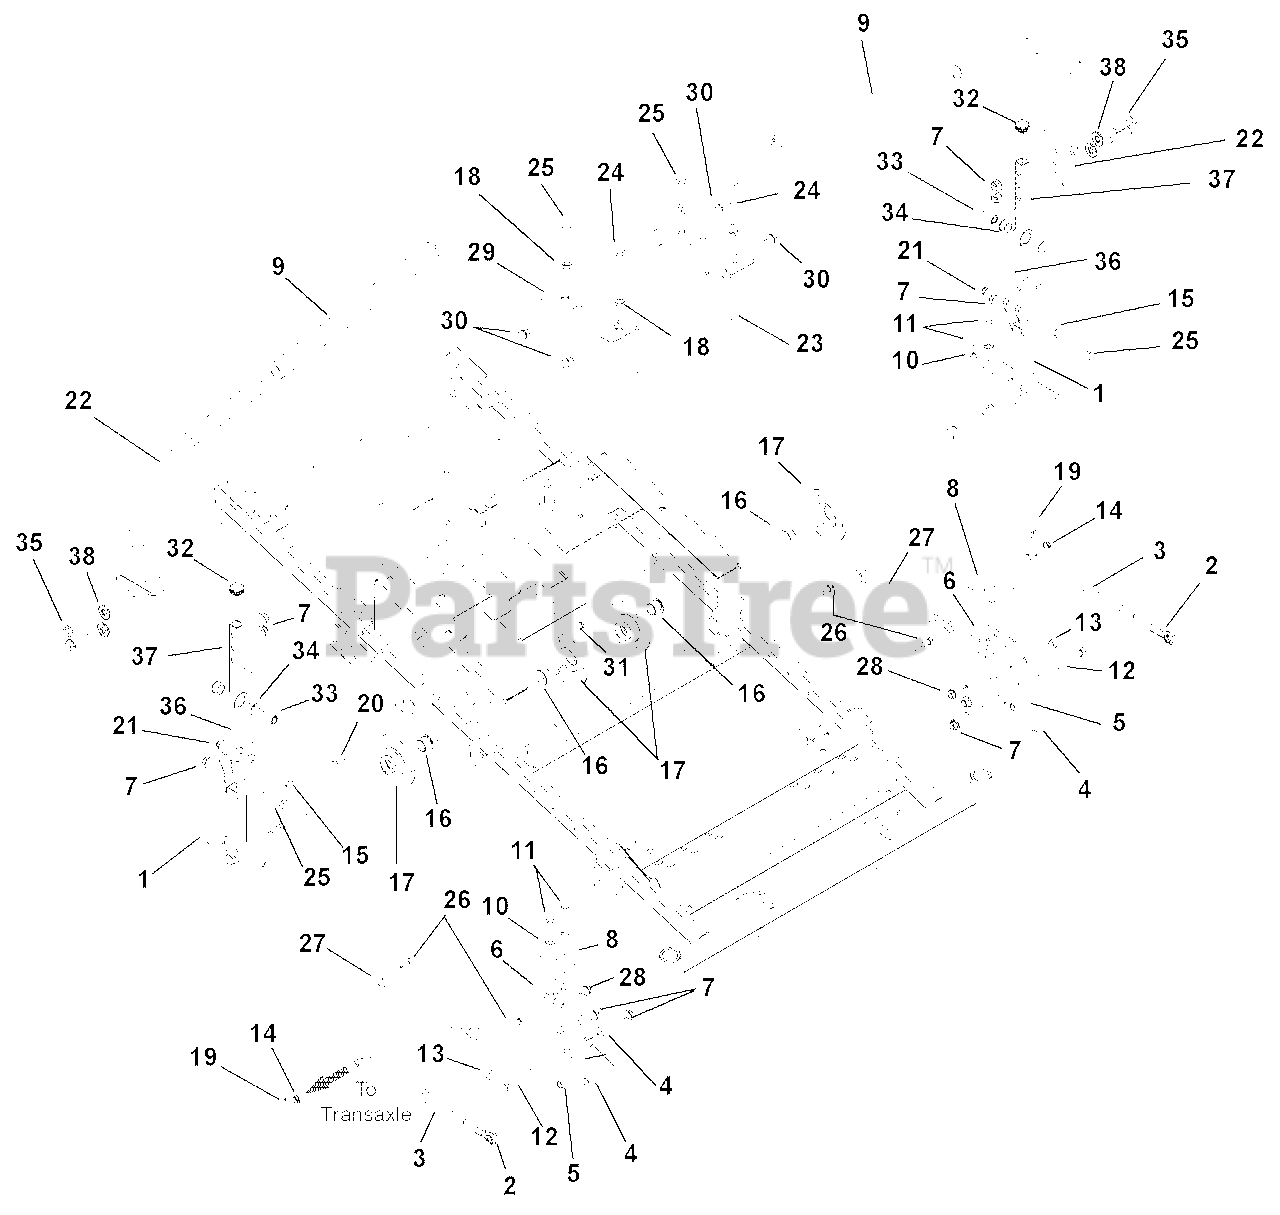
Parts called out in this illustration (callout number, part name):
1	WMT, CONTROL ARM
2	ROD END, .38 RH
3	LINK, TRANSMISSION
4	BSHG, SPCR .390X.625X1.25 PM
5	SPACER, STEERING
6	BRKT, STEERING
7	@NUT-LK-NYL-FLG .38-16 YWZC
8	PLATE, STEERING REINFORCING
9	GRIP, HANDLEBAR 15" FOAM
10	@WSHR-LK .31X.078 REG YWZC
11	BLT-HEX .31-18X1.00 GR8 YWZC
12	@BLT-HEX .38-16X3.75 GR5 YWZC
13	@BLT-HEX .38-16X2.50 GR5 YWZC
14	BUSHING, POLYLINER-.38 SNAPIN
15	@BLT-HEX .31-18X1.75 GR5 YWZC
16	BSHG-FLG .750X1.000X.625X1.250
17	BEARING FLANGE
18	NUT-HEX-JAM .375-16 YWZC
19	PIN-HAIR INT .08X.18X1.18 YWZC
20	@BLT-HEX .25-20X.75 GR5 YWZC
21	@NUT-LK-NYL-FLG .31-18 YWZC
22	WMT, STEERING HANDLE RH
22	WMT, STEERING HANDLE LH
23	BRACKET, LH SPEED CONTROL
24	BLT-HEX .38-16X3.00 GR5 FTH YZ
25	BLT-HEX .375-16X1.750 FTD YWZC
26	STUD- BALL
27	DAMPER, CONTROL
28	@NUT-LK-TOP-FLG .31-18 YWZC
29	BRACKET, RH SPEED CONTROL
30	@SCR-TAP .31-18X.50 HWH TR YWZ
31	@NUT-LK-TOP-FLG .25-20 YWZC
32	CAP PLUG, SQ 3/4-14-20 RIBBED
33	SPACER, .375X.625X.970 (PM)
34	BSHG-FLG, .625X.75X.450X.875
35	BLT-SERHFWH .375-16X1.25 YWZC
36	BSHG, ECCENTRIC .328X.750X.970
37	WMT, UPPER CONTROL ARM
38	@WSHR-FL-STL.406X.812X.065 YWZ
